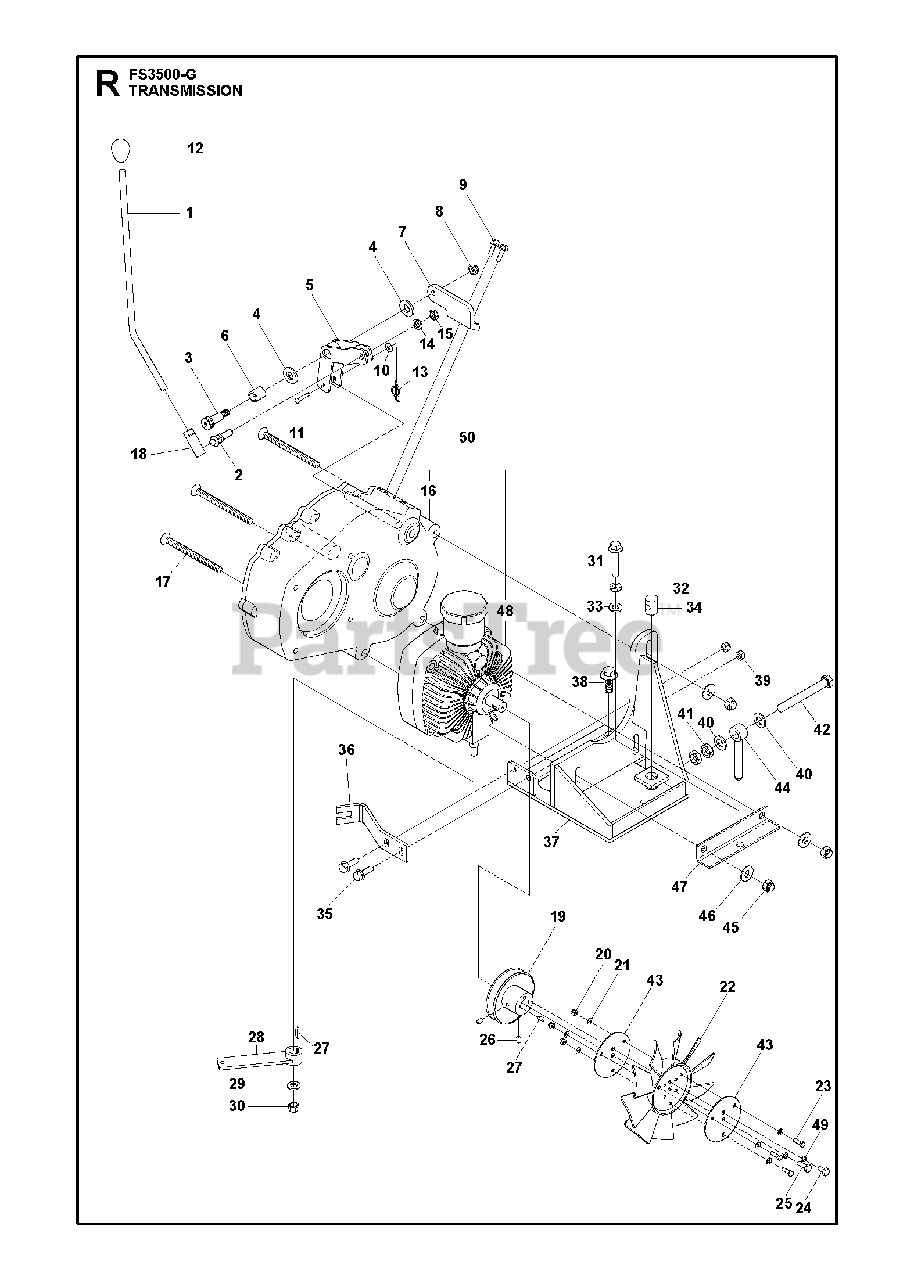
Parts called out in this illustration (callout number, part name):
14	WASHER
20	HEXAGON LOCKING NUT
21	WASHER
24	HCS ¼-20 X ½ GR 5 ZD
29	WASHER
30	NUT
33	WASHER
35	SCREW EHHFM
39	HEXAGON LOCKING NUT
40	WASHER
45	HEXAGON LOCKING NUT
48	HYDROSTATIC PEDAL ASSY
